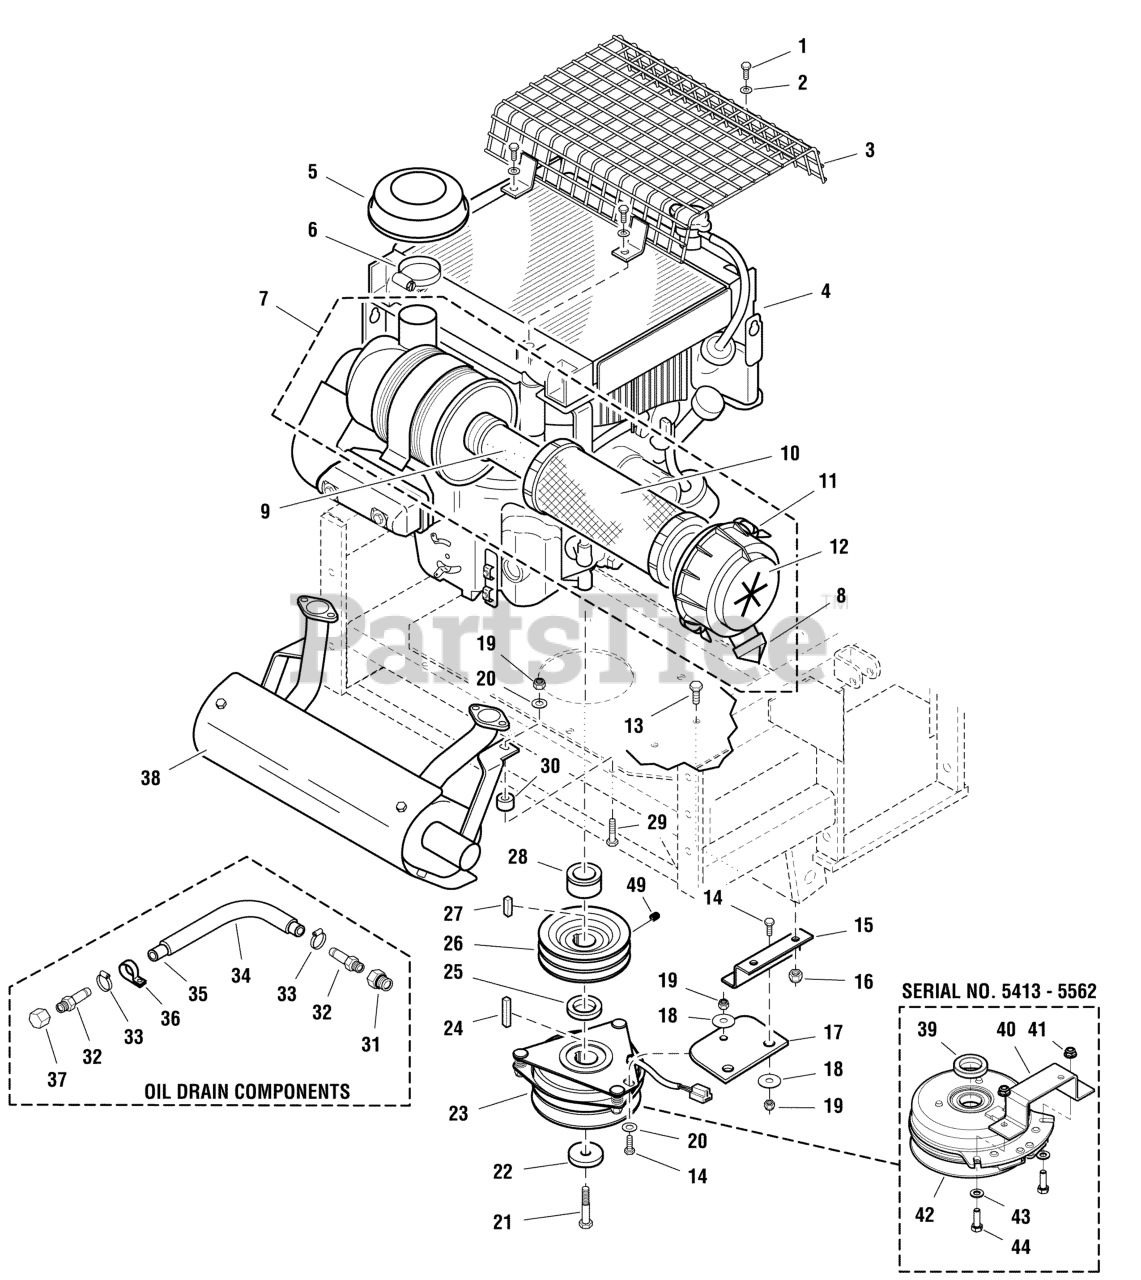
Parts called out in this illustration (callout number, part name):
1	BOLT, M6 x 14MM
2	WASHER, 1/4 SAE
3	RADIATOR PROTECTION SCREEN
5	RAIN CAP
7	AIR FILTER ASSEMBLY, Complete
8	RUBBER, Dust Valve
9	AIR FILTER, Secondary
10	AIR FILTER, Primary
11	CLAMP, Cap
12	CAP, FIlter Case
13	BOLT, 3/8-16 X 1" GD5 CZ
14	BOLT, 5/16-18 X 3/4 GD5
15	ANCHOR, CLUTCH - BLK
16	NUT, 3/8-16 HEX NYLON LOCK
17	CLUTCH ANCHOR PAD
18	WASHER, 3/8" Fender
19	NUT, 5/16-18 Hex Nylon Lock
20	WASHER, 5/16" SAE
21	CRANKSHAFT BOLT, M10 x 65MM
22	SPACER, .45 x 1.88 x .38
23	CLUTCH, OGURA, 250 ft lbs - 1.13"
24	KEY, 1/4 SQ. X 2
25	SPACER, 1.13 x 2.00 x .19
26	CRANKSHAFT PULLEY
27	KEY, 1/4 SQ. X 1
28	SPACER, 1.13 x 1.75 x 1.03
29	BOLT, 5/16-18 x 1-1/2
30	SPACER, .39 x 1.00 x .80
31	ADAPTER, Oil Drain
32	FITTING, 3/8NPT-1/2" Hose, Straight
33	CLAMP, #6 Hose
34	WIRE LOOM, 12"
35	HOSE, 14"
36	CLAMP, Vinyl
37	CAP, 3/8 NPT
38	MUFFLER, KAWASAKI LC
39	SPACER, 1.13 x 1.75 x .32
40	CLUTCH ANCHOR
41	NUT, 5/16-18 Hex Nylock Flange
42	ELECTRIC CLUTCH
43	WASHER, 5/16" SAE
44	BOLT, 5/16-18 x 1"
49	SET SCREW, 5/16-18 X 3/8, KNURL, W/PATCH
